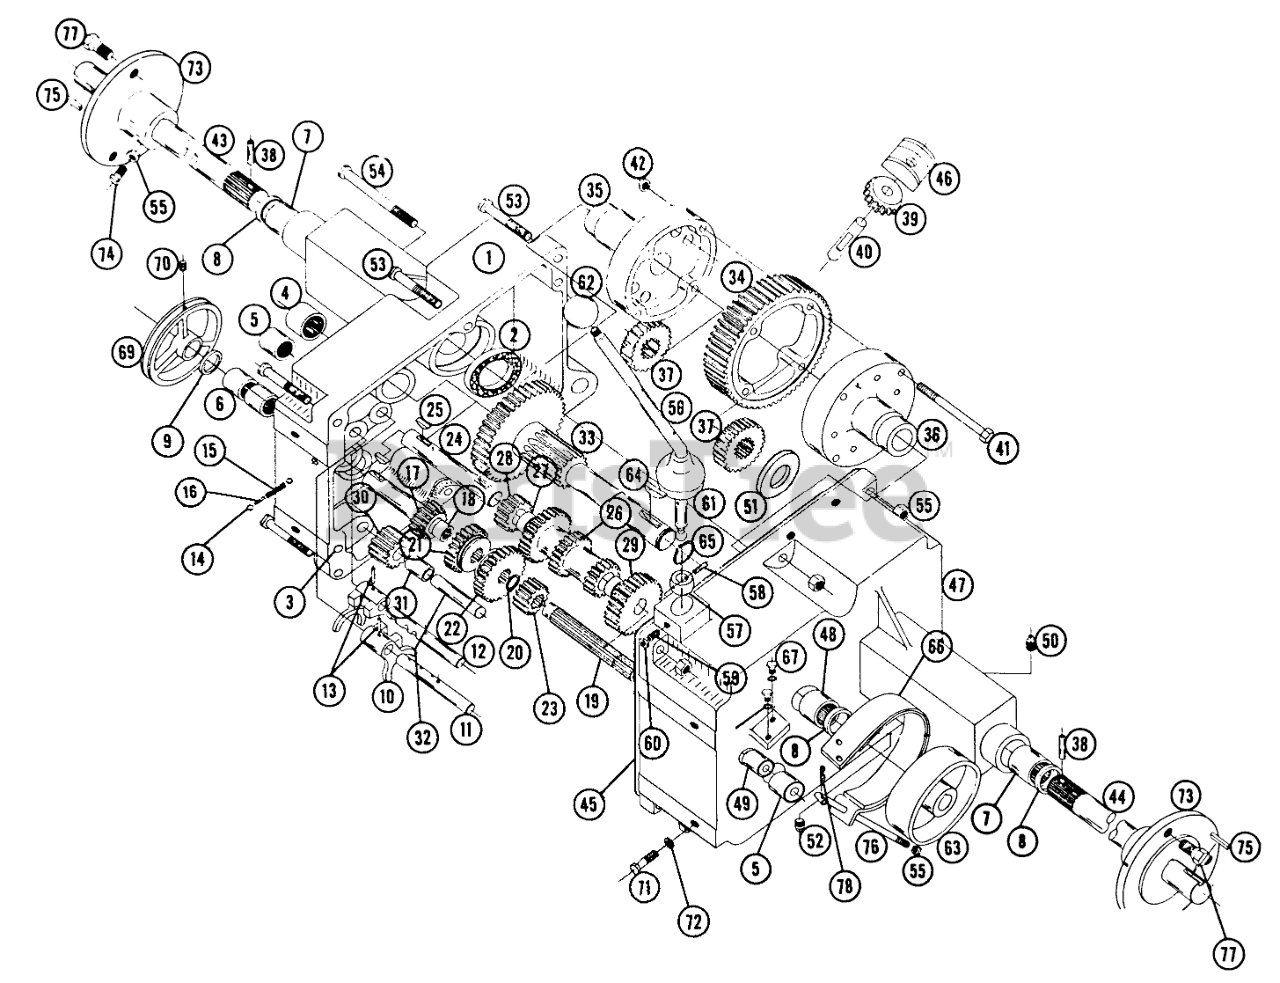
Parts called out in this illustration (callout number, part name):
3	PIN-DOWEL
4	BEARING-NEEDLE
5	BEARING-NEEDLE
10	FORK-SHIFT
13	PIN-ROLL
14	BALL-DETENT
18	BEARING-NEEDLE
20	Snap Ring 3/4 I.D.
23	GEAR
25	Key
27	BUSHING-BRONZE
29	GEAR-CLUSTER SHAFT
30	GEAR/BUSHING ASM-REVERSE IDLER
31	BUSHING
32	PIN-DIFFERENTIAL
34	GEAR DIFF BULL
35	DIFF CASE RH
41	Bolt - Hex 3 3/8 16 x 4
42	Nut-Hex Lock 3/8-16
43	Clevis
45	GASKET-TRANSMISSION
46	BLOCK
50	Plug 1/4 Pipe
52	Plug 3/8 Pipe
53	Bolt, 3/8 16 x 2
54	Bolt Hex 3/8-16 x 1
56	Stick-Shift (4483)
58	Roll Pin
59	Screw Soc. Hd.-Set 1/4-20 x 3/4
60	Nut-Nylok
61	COVER-DUST
64	KEY-WOODRUFF
65	Snap Ring 1" Shaft
67	Bolt-1/4-20 x 5/8
68	Lockwasher
70	Set Screw 5/16-18 x 5/16
71	Bolt 3/8-16 x 1
72	Lockwasher
74	Set Screw-3/8-16 x 1
76	Rod
77	BOLT-LUG, WHEEL
78	Hairpin
